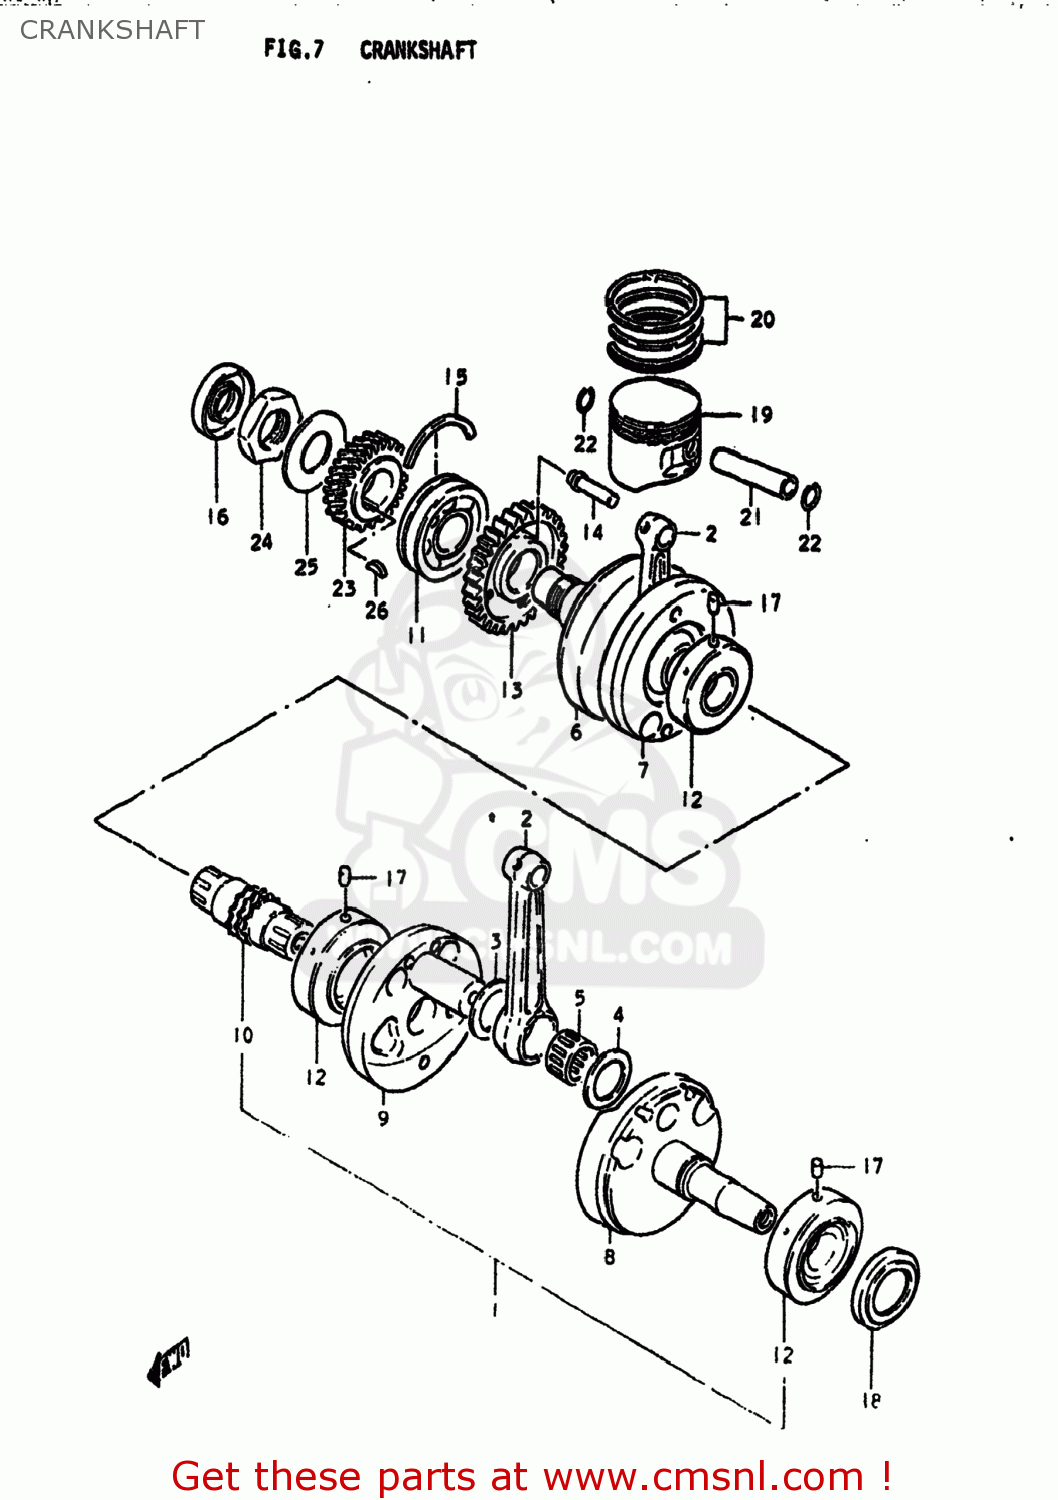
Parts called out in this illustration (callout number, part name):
1	CRANKSHAFT ASSEMBLY
2	ROD,CONNECTING
3	WASHER (28X48X2)
4	WASHER(28X48X1)
5	BEARING(28X38X19.8)
6	CRANKSHAFT
7	WEB,CRANK
8	CRANKSHAFT,LEFT
9	WEB,CRANK
10	SHAFT,TIMING CHAIN DRIVE
11	BEARING(30X72X19)
12	BEARING
13	GEAR,CRANK BALANCER DRIVE
14	PIN
15	C RING
16	SEAL,OIL(25X47X8)
17	PIN
18	OIL SEAL
19	PISTON (67.00MM)
20	RING SET,PISTON
21	PIN,PISTON
22	CIRCLIP
23	GEAR,PRIMARY DRIVE
24	NUT
25	WASHER
26	KEY
